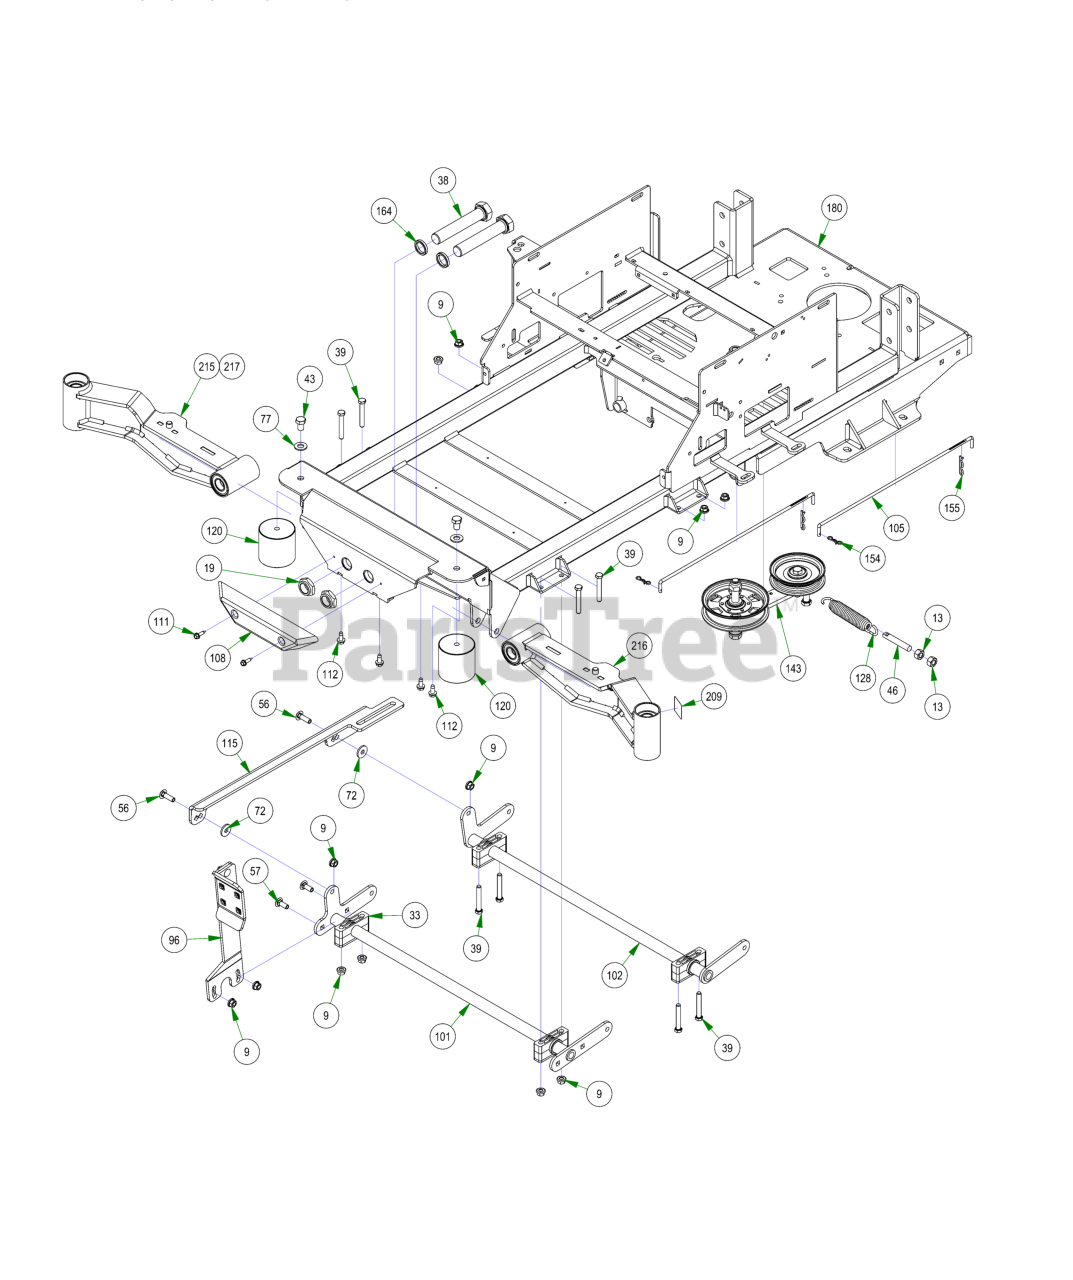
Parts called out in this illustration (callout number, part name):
9	3/8-16 NYLON INSERT FLANGE LOCKNUT (GR.F) ZINC
13	1/2-13 HEX NUT ZINC
19	1"-14 NYLON INSERT JAM LOCKNUT ZINC
33	Pillow Block Kit
38	1"-14 X 5-1/2 HEX CAP SCREW (GR.8) ZINC YELLOW
39	3/8-16 X 2-1/2 HEX CAP SCREW (GR.5) ZINC
43	1/2-13 X 3/4 HEX CAP SCREW (GR.5) ZINC
46	All Thread
56	3/8-16 X 1-1/4 CARRIAGE BOLT ZINC
57	3/8-16 X 1 CARRIAGE BOLT (GR.5) ZINC
72	.390 ID X 1.12 OD X .125 THK FLAT WASHER NYLON
77	1/2 SAE FLAT WASHER (1-1/16" OD) GR.8 ZINC YELLOW
96	Foot Pedal Assembly
101	Actuator Bar Front- 2017 MZ/ZT
102	Actuator Bar Rear- 2017 MZ/ZT
105	Neutral Rod
108	Bumper EZT
111	1/4 x 1 Hex Head Tek Screw
112	5/16-18 X 3/4 HEX WASHER SLOT (F) TCS ZINC
115	2017 MZ/ZT Actuator Linkage
120	Vibration Mount- Red Dot
128	Deck Idler Spring
143	Maverick Pump Idler
155	Neutral Rod Clip
164	Spacer, 1x1.375x.25
180	2022 Maverick Frame - Painted
192	Patent Decal
209	Independetly Articulating Front Suspension Arms Patent Decal
215	2021 Maverick RH Short Front Suspension Arm Assy (48")
216	2021 Maverick LH Front Suspension Arm Assy (48", 54" & 60")
217	2021 Maverick RH Long Front Suspension Arm Assy (54" & 60")
